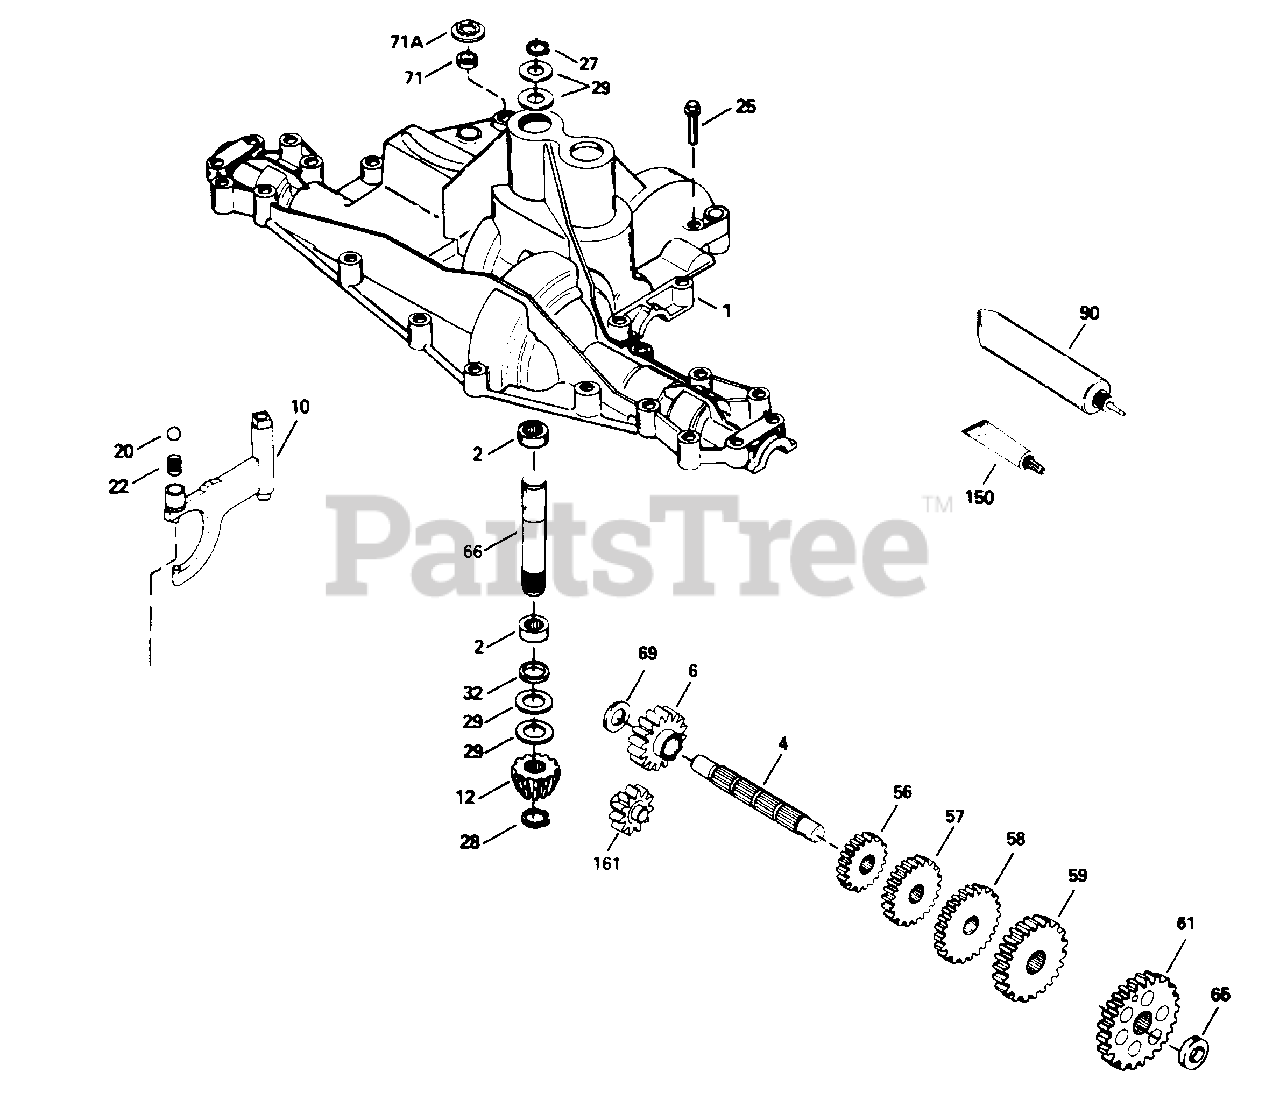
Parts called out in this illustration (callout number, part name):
1	Transaxle Cover
4	Countershaft
6	Spur Gear (16 Teeth)
10	Shift Rod & Fork
12	Bevel Pinion (14 Teeth)
20	Ball (3/8" dia.)
27	Retaining Ring
28	Retaining Ring
56	Spur Gear (15 Teeth)
57	Spur Gear (23 Teeth)
58	Spur Gear (21 Teeth)
59	Spur Gear (30 Teeth)
61	Spur Gear (34 Teeth)
66	Input Shaft (3.522" lg.)
69	Thrust Washer
71	Square Cut Ring
71A	Pushnut
90	Grease (32 oz. btl. Bentonite grease)
150	Gasket Eliminator (Loctite #515)
161	Reverse Idler Assembly
